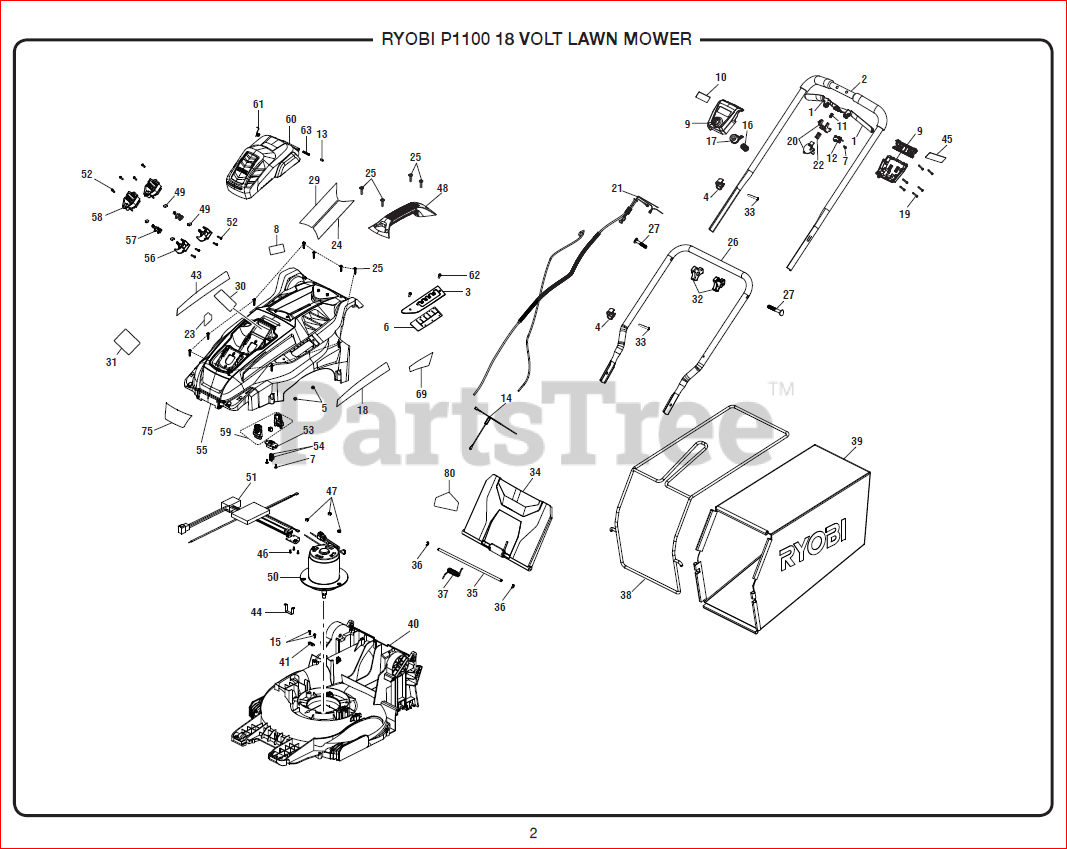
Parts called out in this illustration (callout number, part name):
1	Trigger Assembly
2	Upper Handle Assembly
3	Height Adjustment Plate
4	Cord Clamp
5	Lock Nut (M5 x 0.8 mm)
6	Dust Gasket
7	Screw (M4 x 10 mm, T20 Torx Pan Hd.)
8	Data Label
9	Trigger Housing Assembly
10	Ryobi Logo Label (Handle)
11	Compression Spring (Trigger)
12	On/Off Switch
13	Battery Door Axle
14	Lead Wire w/Terminal Block
15	Screw (M4 x 16 mm, T20 Torx Pan Hd.).
16	Handle Adjustment Spring
17	Safety Button
18	Lithium Label (Left)
19	Screw (M4-18 x 30 mm, T15 Torx Soc. Hd.)
20	Switch Button Assembly
21	Starter Cable (Long)
22	Compression Spring (Trigger Handle)
23	Battery Lens Label
24	Warning Icon Label (Right)
25	Screw (M4 x 20 mm, T20 Torx Pan Hd. S.T.)
26	Lower Handle
27	Screw (M8 x 57 mm)
29	Warning Icon Label (Left)
30	Start Key Label (Eng)
31	Start Key Label (FR/SP)
32	Knob (526906001)
33	Screw (M3 x 20 mm, Pan Hd.)
34	Rear Discharge Door Assembly
35	Rear Door Axle
36	Retaining Ring (E)
37	Torsion Spring (Rear Door)
38	Bag Frame
41	Wire Press Plate
43	Lithium Label (Right)
44	Mounting Bracket
45	Starting Instructions Label
46	Screw (M3 x 8 mm, Pan Hd., Pan Hd)
47	Lock Nut (M6)
49	Rubber Cushion
51	Soft Start Circuit Board
52	Screw (M4 x 16 mm, T15 Torx Pan Hd.)
53	Key Holder
54	Female Terminal
55	Deck Cover Assembly w/Labels
56	Press Cover (Battery Connect)
57	Plate (Battery Connect)
58	Base (Battery Connect)
59	Start Key
60	Battery Cover
61	Torsion Spring (Battery Door)
62	SCREW (M5 x 16 mm SOC. WASHER HD. CAP)
63	Compression Spring
69	Cut Height Label
75	Ryobi Logo Label (Handle)
80	Danger Label (No Hands/Feet)
